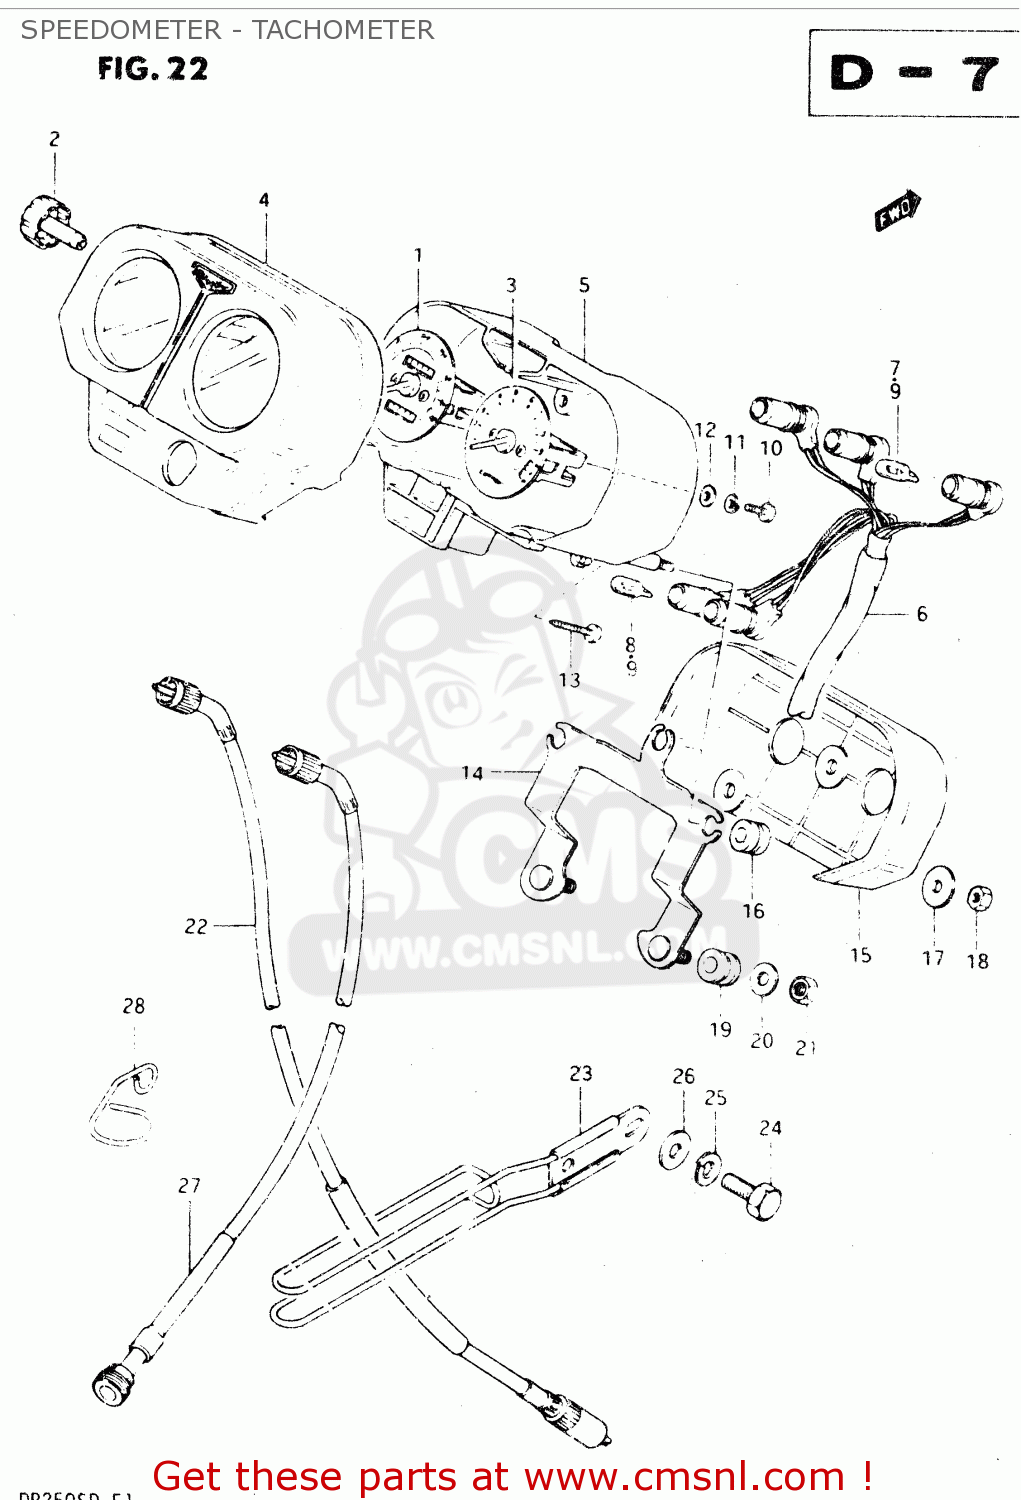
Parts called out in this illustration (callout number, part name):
1	SPEEDOMETER
2	KNOB,TRIP
3	TACHOMETER
4	HOOD, METER
5	CASE,INNER
6	SOCKET
7	BULB(6V1.7W,STANLEY,A61A)
8	BULB(6V,3W)
9	BULB(12V3.4W,T10)
10	SCREW 4X10
11	LOCK WASHER
12	WASHER
13	SCREW
14	BRACKET
15	COVER
16	CUSHION
17	WASHER (5.5X16X1.2)
18	NUT
19	CUSHION
20	WASHER
21	NUT
22	CABLE ASSY,SPE
23	GUIDE,CABLE
24	BOLT 8X12
25	LOCK WASHER
26	WASHER
27	CABLE ASSEMBLY,TACHOMETER
28	GUIDE
